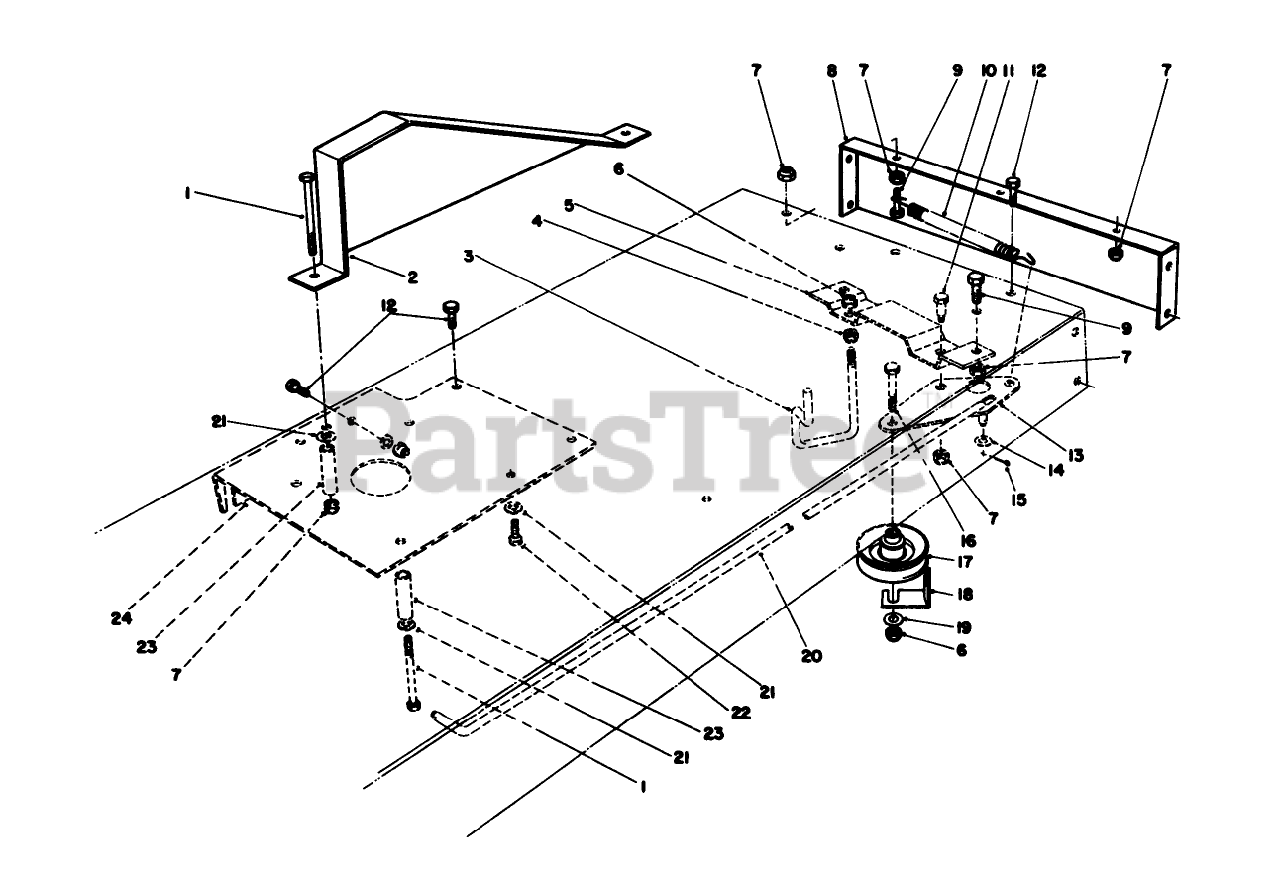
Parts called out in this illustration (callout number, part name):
1	SCREW-HH
3	Guide-Belt
4	NUT-LOCK, SIDE
6	NUT-LOCK, CONE
7	NUT-LOCK, NI
8	REAR FRAME *R
9	SCREW-HH
10	TRACTION SPRING
11	BOLT-SHOULDER
12	SCREW-HH
13	Bracket-Traction Pivot
14	WASHER-FLAT
15	PIN-COTTER
16	SCREW-HH
17	PULLEY-IDLER
19	WASHER-FLAT
20	TRACTION ROD
21	WASHER-PLAIN
22	5/16-18X3/4 HX HD SEM
